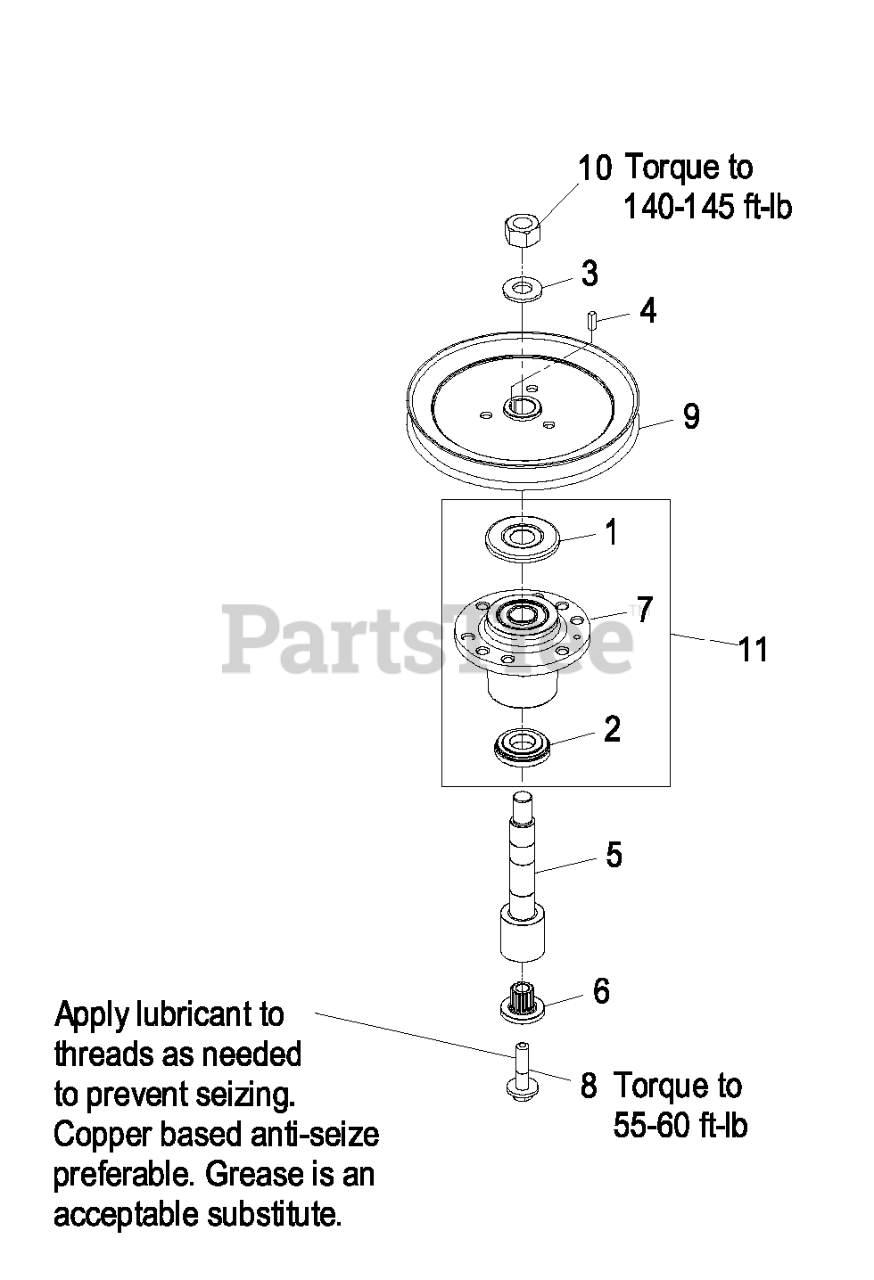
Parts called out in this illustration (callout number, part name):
1	GUARD-BEARING, TOP
2	SPACER-GUARD, BOTTOM
5	KIT, SPLINED SPINDLE 103-
6	BUSHING,SPLINED
8	SCREW,SEMS 1/2-20 X 2.19
9	SHEAVE,BLADE DRIVE 8.74
11	KIT, CUTTER HOUSING
